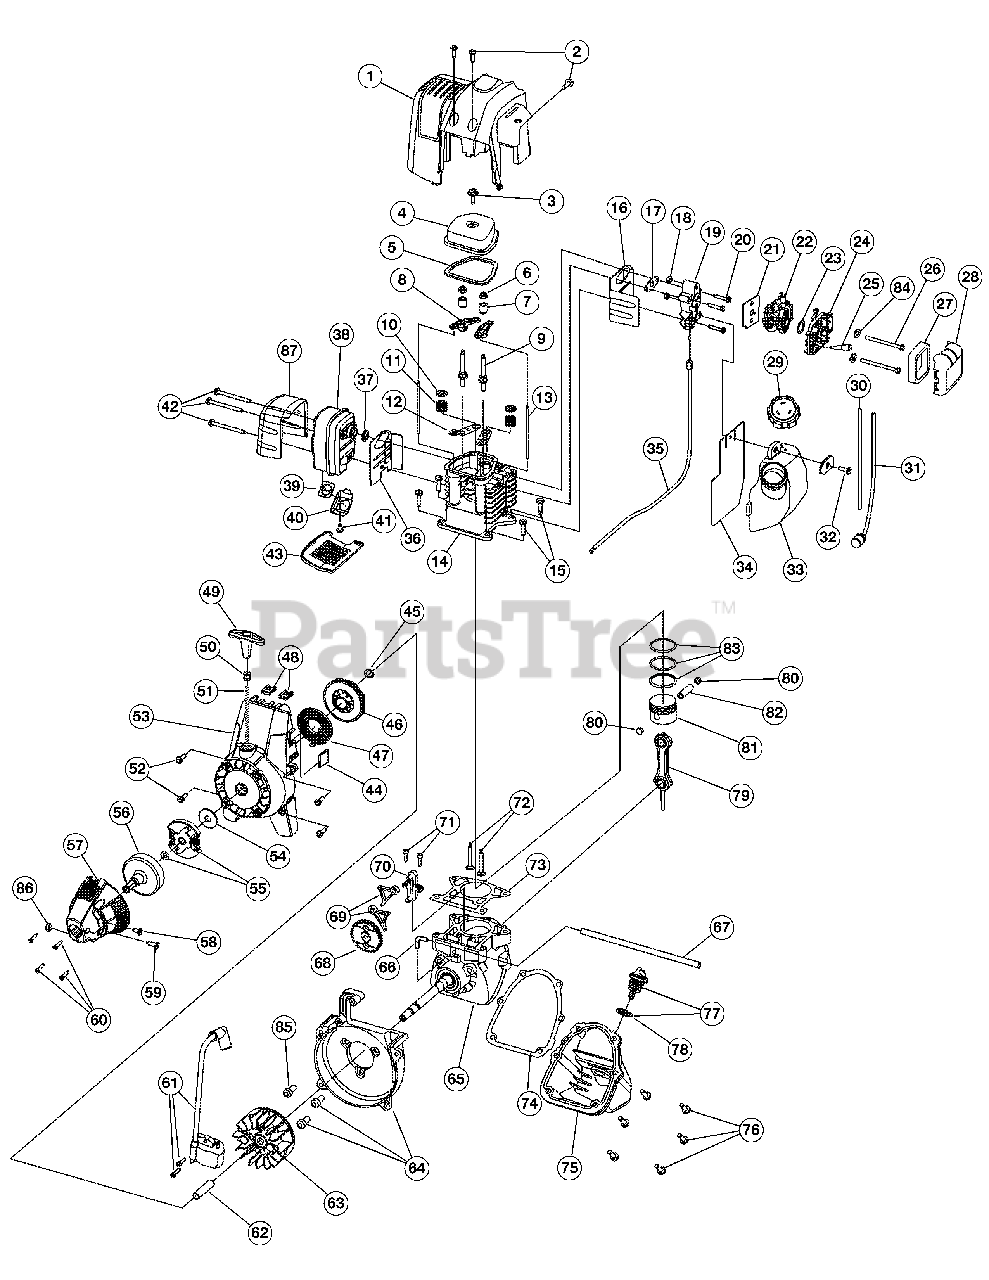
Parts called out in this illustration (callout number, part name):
1	Engine Cover
2	Engine Cover Screws
3	Valve Cover Screw
4	Valve Cover
5	Valve Cover Gasket
6	Rocker Adjustment Nut
7	Rocker Arm Pivot
8	Rocker Arm
9	Rocker Arm Stud
10	Valve Spring Retainer
11	Valve Spring
12	Push Rod Guide
13	Push Rod
14	Cylinder Head (includes 9-12)
15	Cylinder Screw
16	Intake Baffle
17	Carburetor Mount Gasket
18	Nut
19	Carburetor Mount (includes 18)
20	Carburetor Mount Screw
21	Carburetor Gasket
22	Carburetor with Primer
23	O-Ring, Carburetor
24	Air Filter Assembly (includes 27 & 28)
25	Breather Tube
26	Air Filter Mounting Screw
27	Air Filter
28	Air Filter Cover
29	Fuel Cap
30	Fuel Return Line
31	Fuel Pick-Up Line with Filter
32	Screw
33	Fuel Tank Assembly
34	Fuel Tank Shield
35	Throttle Cable
36	Muffler Baffle
37	Muffler Gasket
38	Muffler (includes 37 & 39-41)
39	Spark Arrestor Screen
40	Screen Cover
42	Muffler Mounting Screw
43	Muffler Cover
44	Grommet
45	Pulley Retainer
46	Recoil Pulley
47	Recoil Spring
48	Nut Clip
49	Pull Handle
50	Rope Guide
52	Starter Housing Screw
53	Starter Housing Assembly (includes 45-52)
54	Clutch Washer
55	Clutch with Spacer
56	Clutch Drum
57	Clutch Cover
58	Anti-Rotation Screw
59	Screw
60	Clutch Cover Screw
61	Ignition Module with Screws
63	Flywheel
64	Shroud Assembly w\Screws
65	Crankcase Assembly (includes 66 & 67)
66	90° Elbow
67	Breather Hose
68	Cam Gear
69	Cam Follower
70	Cam Bracket
71	Cam Bracket Screw
72	Valves, Intake and Exhaust
73	Cylinder Gasket
74	Oil Pan Gasket
75	Oil Pan (includes 74 & 76)
76	Oil Pan Screw
77	Dipstick Assembly (includes 78)
79	Connecting Rod
80	Wrist Pin Button
81	Piston
82	Wrist Pin
83	Piston Ring Set
87	Muffler Shield
